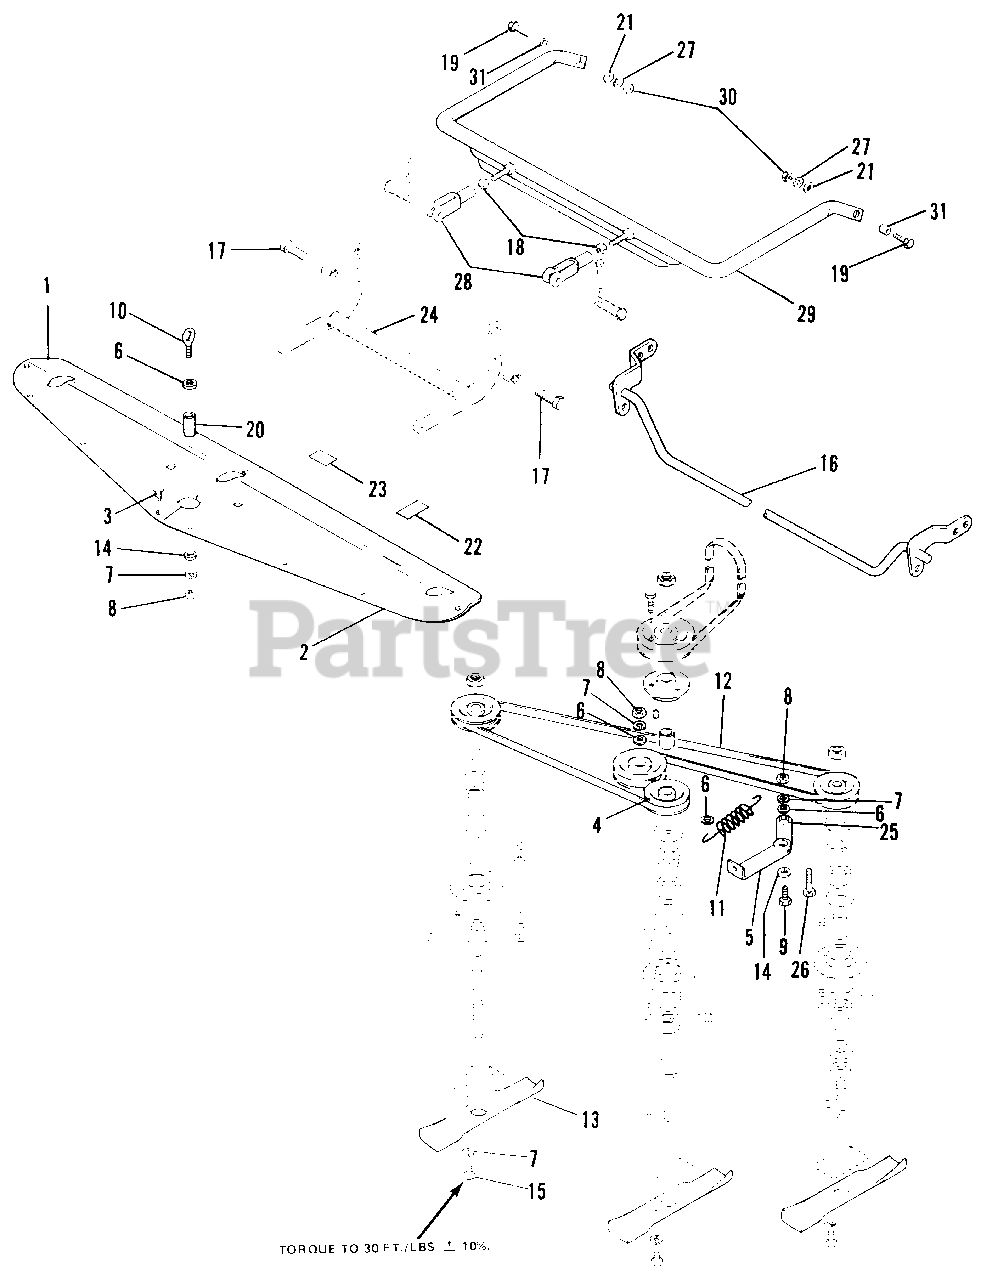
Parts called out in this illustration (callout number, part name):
1	COVER, R.H.
2	COVER, L.H.
3	SCREW, Hex, Taptite, 1/4-20 x 3/8
4	PULLEY, Idler
5	LEVER ASSY, Idler
6	WASHER, Plain, 5/16
7	LOCKWASHER, Spring, 3/8
8	NUT, Hex, 3/8-16
11	SPRING, Tension
12	BELT, "V", Mower Drive
13	BLADE, Knife
14	WASHER, Plain, 3/8
15	CAPSCREW, Hex Hd., 3/8-16 x 5/8
16	ARM ASSY, Rocker
17	CAPSCREW, Hex Hd., 1/2-20 x 3
18	NUT, Hex, Jam, 1/2-20
19	CAPSCREW, Hex Hd., 1/2-13 x 1-1/4
21	WASHER, Plain, 7/16
22	FILM, Safety
23	FILM, Belt Installation
24	ARM ASSY, Rocker
25	RACE, Inner
26	CAPSCREW, Hex Hd., 3/8-16 x 1-3/4
27	LOCKWASHER, Spring, 1/2
28	YOKE, End Adj.
30	NUT, Hex, 1/2-13
